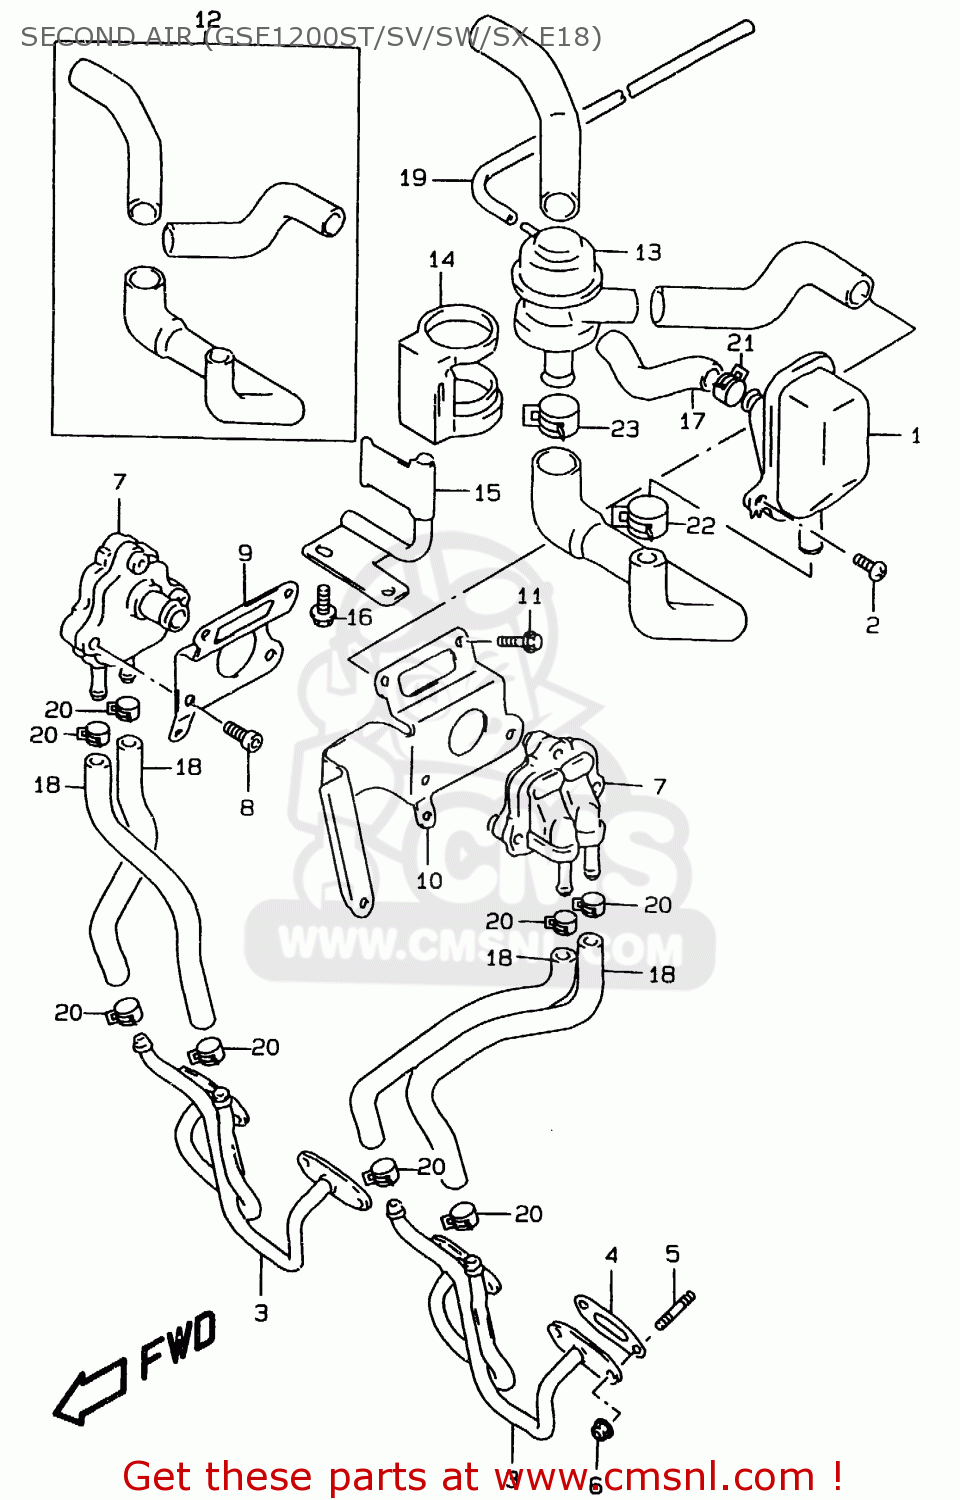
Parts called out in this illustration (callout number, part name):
1	CLEANER ASSY,2ND AIR
2	SCREW
3	PIPE,2ND AIR,L
4	GASKET,SECOND AIR PIPE (NAS)
5	STUD BOLT
6	NUT
7	VALVE ASSY,2ND AIR REED
8	BOLT
9	BRACKET,REED VALVE,RIGHT
10	BRACKET COMP,REED VALVE
11	BOLT
12	HOSE SET,SECOND AIR
13	VALVE ASSEMBLY,SECOND AIR SWITCH
14	CUSHION,2ND AIR VALVE
15	BRACKET COMP,SECOND AIR S
16	BOLT
17	HOSE(12X16X600)
18	HOSE(9X14X600)
19	HOSE(4X7X600)
20	CLIP
21	CLIP
22	CLIP
23	CLIP
